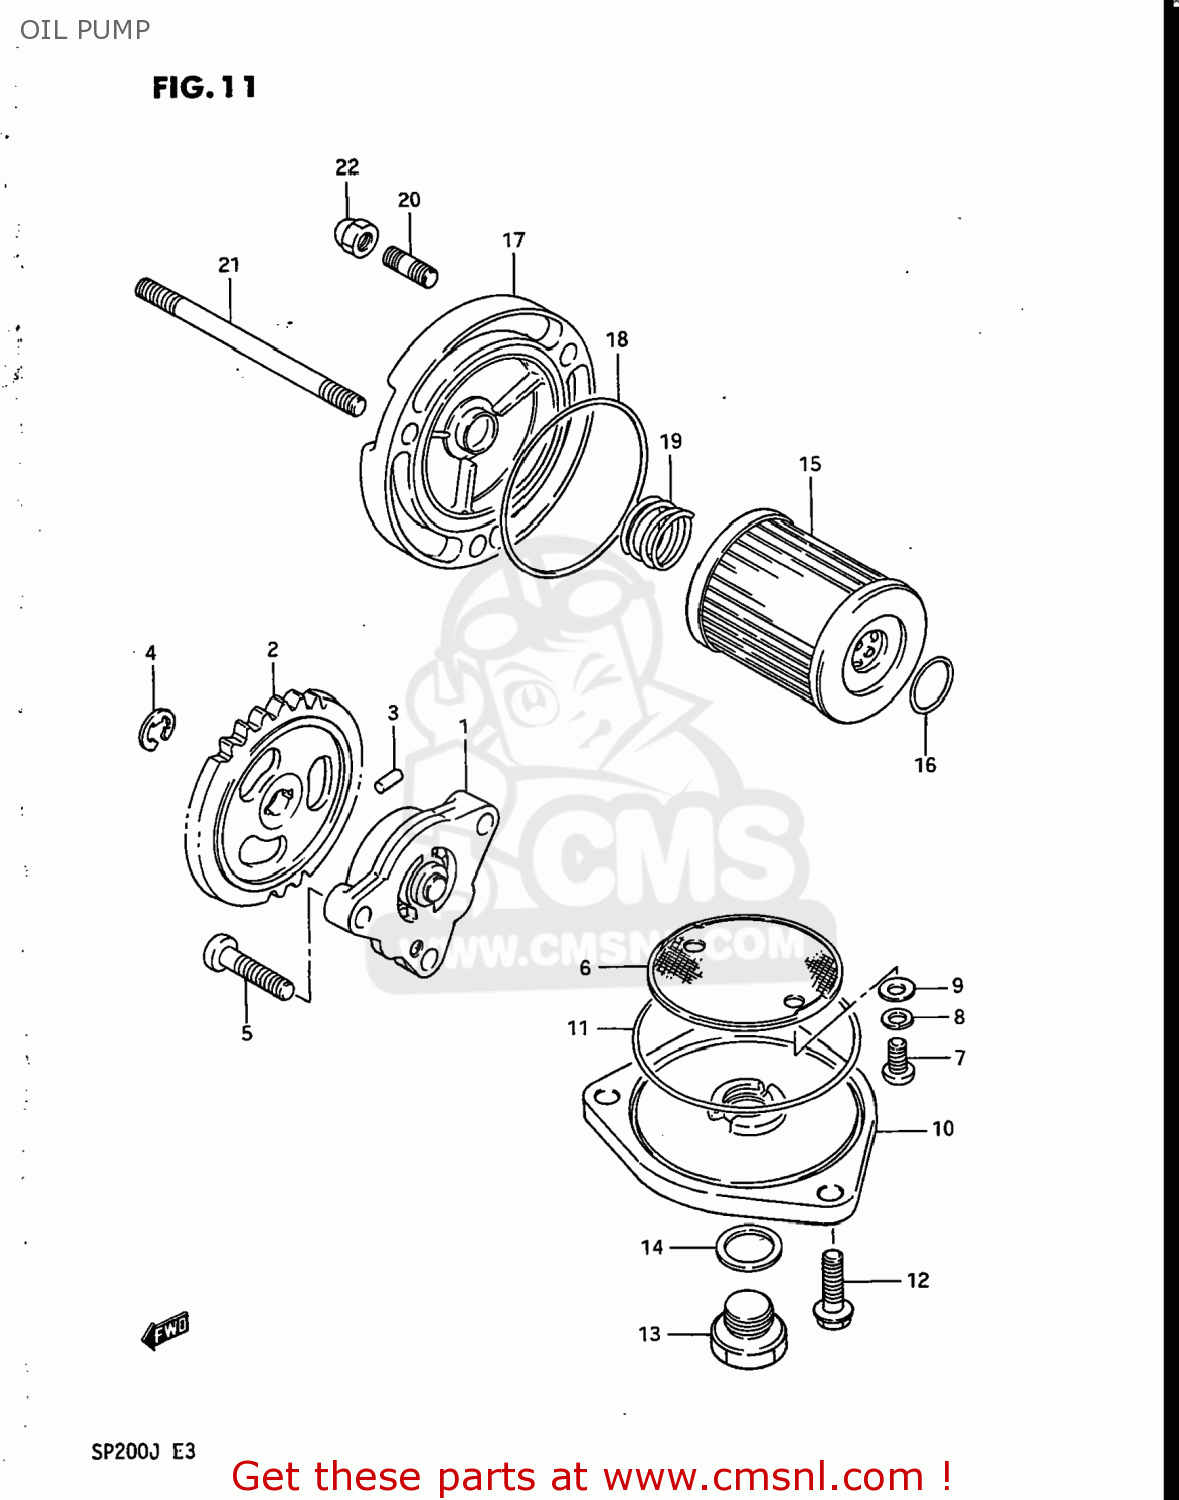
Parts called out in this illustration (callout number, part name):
1	PUMP ASSY,ENGINE OIL
2	GEAR,OIL PUMP DRIVEN (N
3	PIN(2.5X11.8)
4	E RING 6MM
5	SCREW
6	STRAINER,ENGINE OIL
7	SCREW 5X12
8	LOCK WASHER
9	WASHER
10	CAP,OIL STRAINER
11	O RING(D:2.4,ID:60.5)
12	BOLT (6X20)
13	PLUG
14	GASKET(14X19.2X2) (NAS)
15	FILTER,OIL
16	O RING(D:1.9,ID:13)
17	CAP,OIL FILTER
18	O RING(D:2.4,ID:52.6)
19	SPRING
20	STUD 6X12
21	STUD BOLT
22	NUT 6MM
